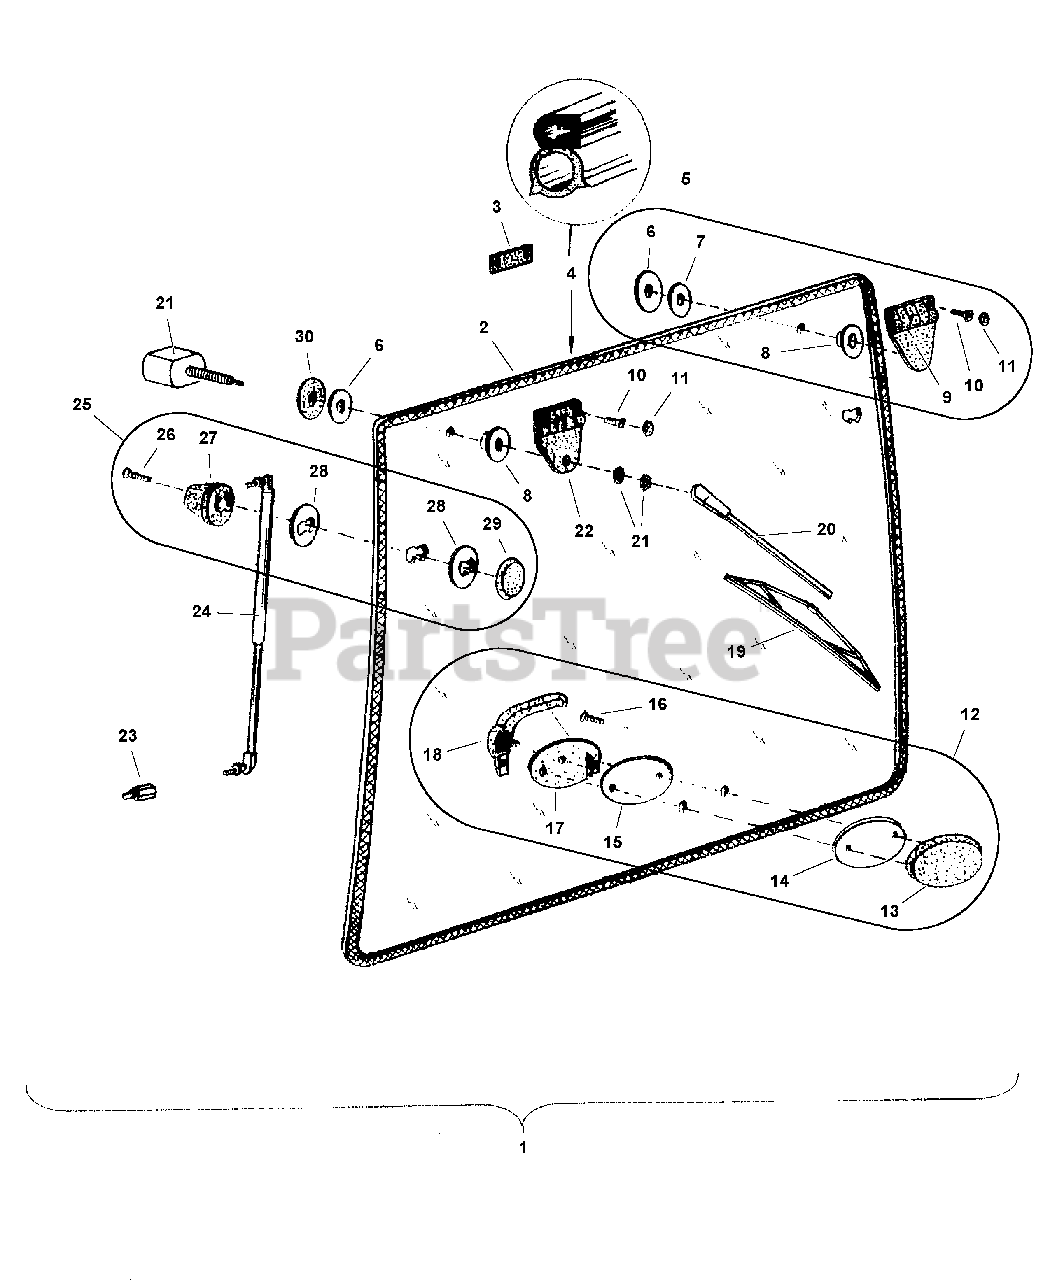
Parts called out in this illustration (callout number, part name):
1	WINDSHIELD, Complete (Includes Ref. 2 - 30)
3	INNER BRACKET, Hinge
4	PROFILE SEALING, 11 ft. 2 in.
5	SET HINGE, (Includes Ref. 6 - 11)
6	WASHER, with Bushing, M8
7	WASHER, Rubber
8	WASHER, Rubber with Socket
9	PVC HINGE, Complete
12	SET LOCKING, (Includes Ref. 13 - 18)
13	SOCKET, Outer Handle
17	SCOKET, Inner Handle
18	HANDLE, Lock
20	ARM, Wiper 300-400
21	MOTOR, Wiper 85/12V, (Includes washers)
22	HINGE, Complete, Drilled
23	GASLIFT SOCKET
24	GASLIFT, 500MM/200N
25	SET GASSPRING SOCKET, (Includes Ref. 26 - 29)
27	BEARING, Inner Gaslift
28	WASHER, Rubber
29	BEARING, Outer Gaslift
30	WASHER, Plastic
